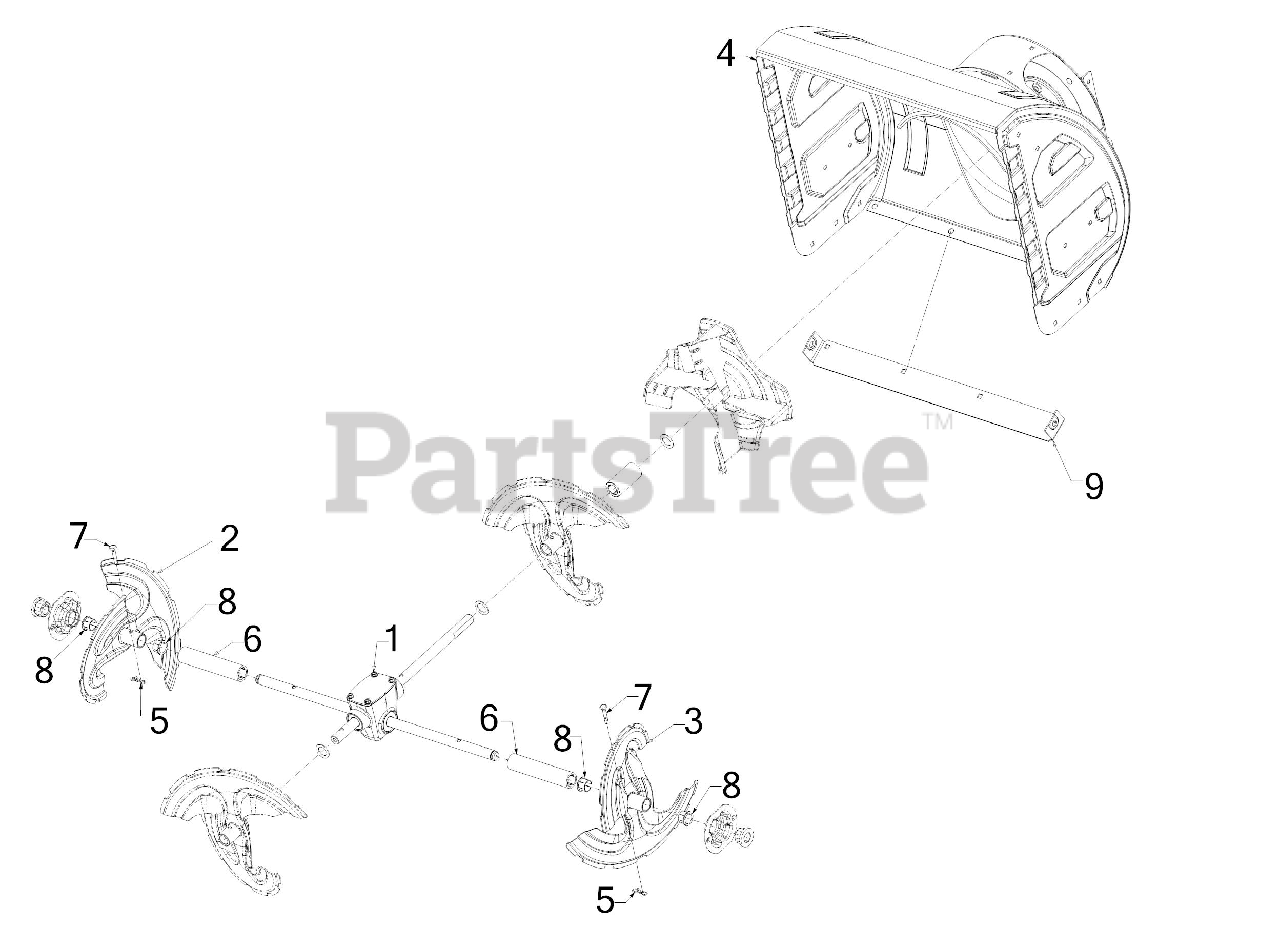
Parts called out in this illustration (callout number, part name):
1	24" AUGER GEARBOX ASSEMBLY
5	BOW TIE COTTER PIN 1/4-5/16
7	SHEAR PIN .25 x 1.50 GR2
8	FLANGE BUSHING
